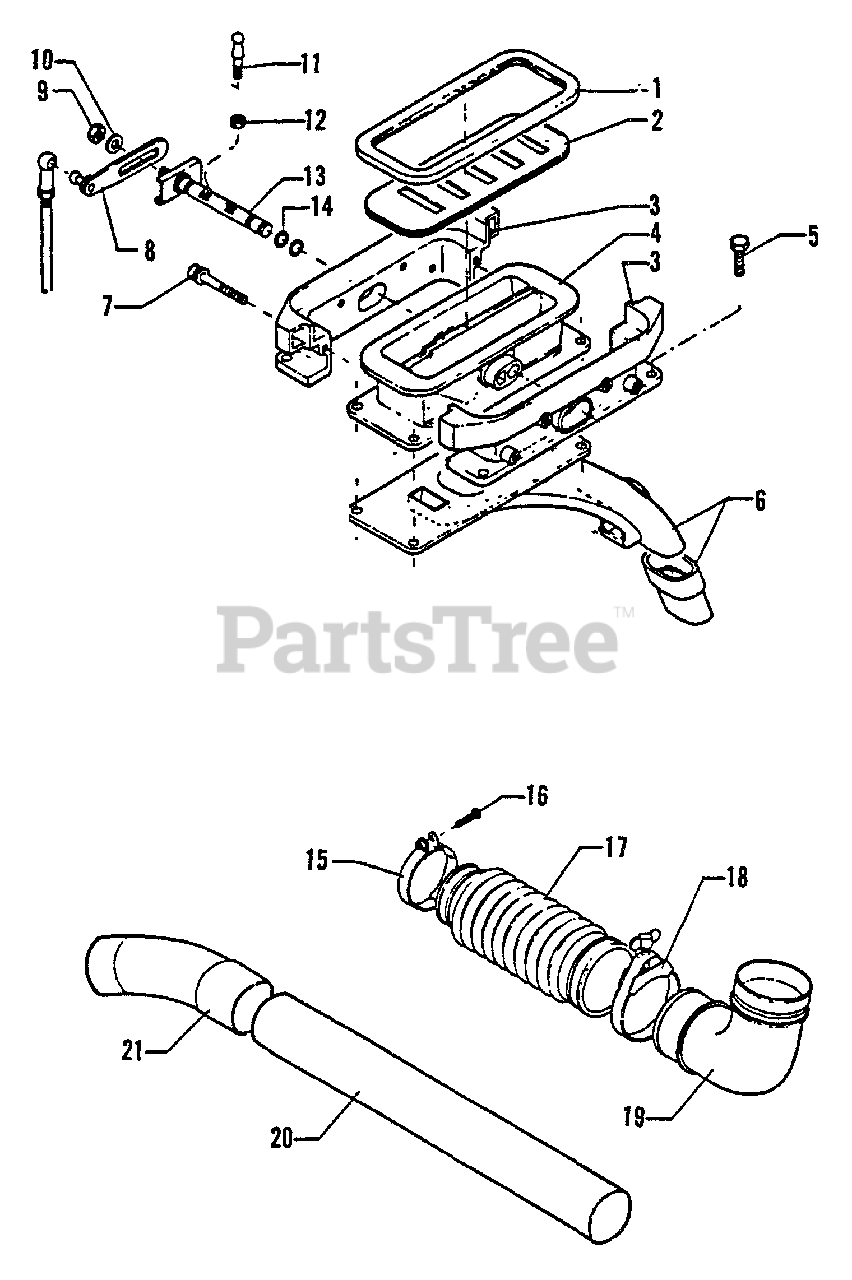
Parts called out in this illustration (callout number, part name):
2	SHUTTER ASSY
3	TANK - LOWER
4	TANK - LOWER
6	TUBE, DUST
7	SCREW 5×30
8	ARM, SHUTTER
9	NUT, HEX M6
10	WASHER 6.5×11.5×0.8
11	JOINT
13	SHAFT, SHUTTER
15	CLAMP KIT
16	SCREW 5×25
17	TUBE, FLEXIBLE
20	TUBE, BLOWER - STRAIGHT
21	TUBE, BLOWER - CURVED
